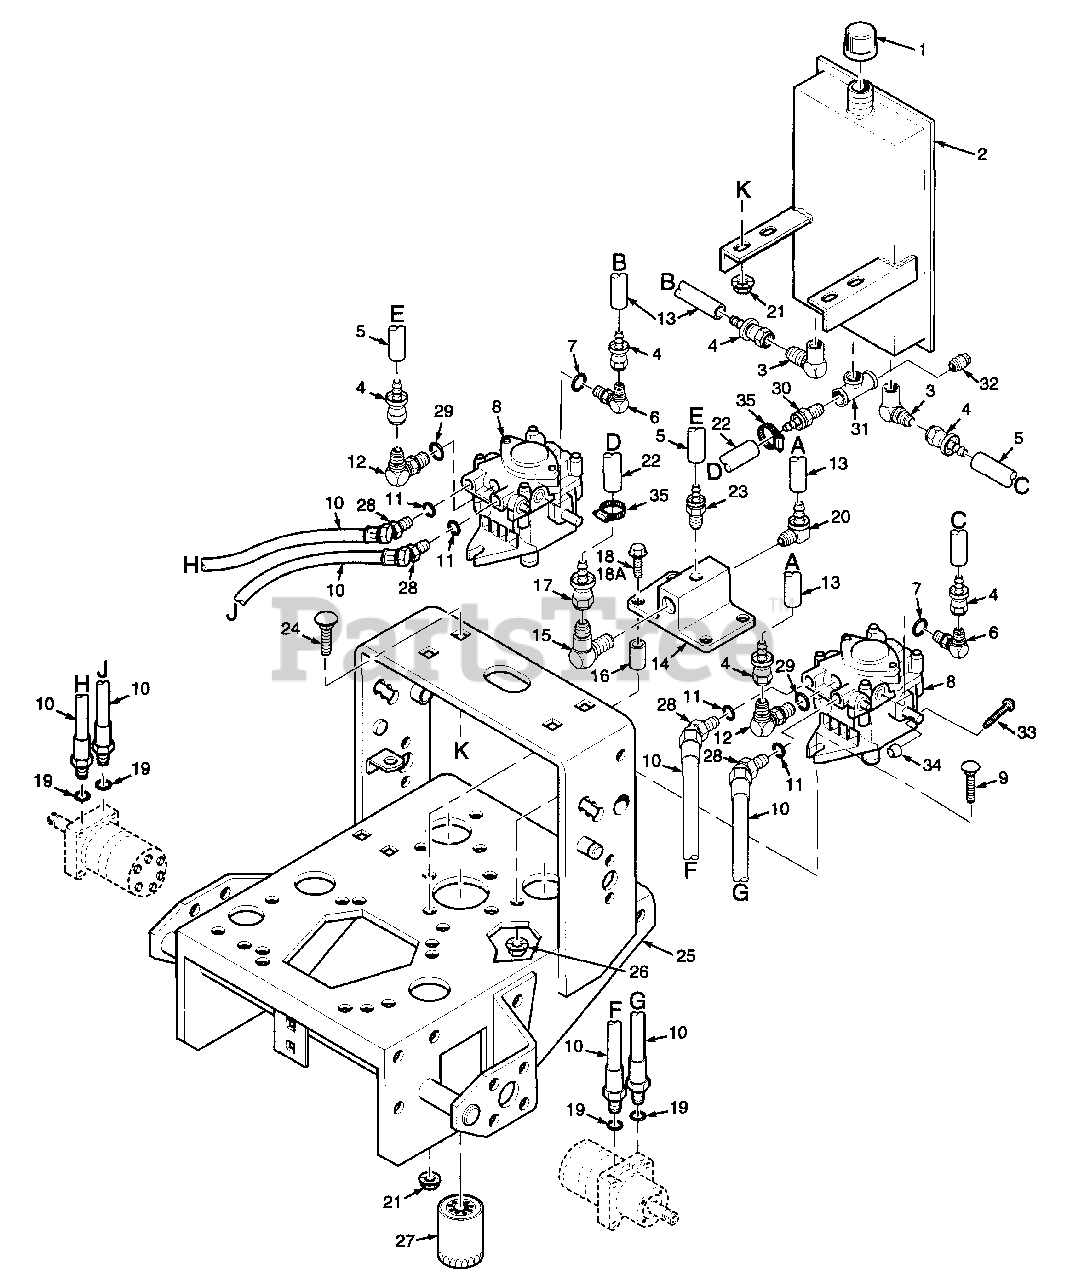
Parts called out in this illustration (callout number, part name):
1	Cap, Oil Reservoir
2	Oil Reservoir (Large Frame)
3	Elbow, 90 deg. Female 1/4 NPT to 1/4 JIC Male
4	Coupling, 7/16-20 SAE Flare Swivel to 1/4" Hose Push On
5	Hose, 1/4" ID - 12" Long
6	Elbow, 90 deg. 7/16-20 JIC to 9/16-18 "O" Ring
7	O-Ring
8	Pump, Hydro-Gear BDP-10L117
9	Bolt, Carriage, 3/8-16 x 1-1/4"
10	Nose, Pump to Motor
11	O-Ring
12	Elbow, 90 deg., 7/16-20 JIC x 7/16-20 O-Ring
13	Hose, 1/4" ID - 10" Long
14	Oil Filter Base
15	Elbow, 90 deg. Male 3/4-16 JIC to 1/2" Male NPT
16	Spacer, Oil Filter Base (20" Frame)
17	Coupling, 3/4-16 SAE to 1/2" Hose Push On
18	Capscrew, 5/16-18 x .75" (For 16") Serr. Flange
18A	Capscrew, 5/16-18 x 2.25" (For 20") Serr. Flange
19	O-Ring
20	Elbow, 90 deg. Male 1/4 NPT to 1/4 Hose Push On
21	Nut, 5/16-18 Serr. Flange
22	Hose, Formed 1/2" ID
23	Coupling, 1/4 straight Male NPT to 1/4 Hose Push On
24	Bolt, 5/16-18 x 3/4" Carriage
25	Engine Deck (16" Wide) W/Decals
26	Nut, 3/8-16 Serr Flange
27	Oil Filter
28	Elbow, 45 Deg. - 3/4-16 JIC Male x Male 3/4-16 O-Ring
29	O-Ring
30	Coupling, 3/8 Pipe to 1/2 Push-on
31	T-Fitting, 3/8 NPT
32	Plug, 3/8-18 NPTF Magnetic
33	Screw, 1/4-20 x 2.0" Round Head Phillips
34	Nut, 1/4-20 Elastic Stop
35	Clamp, .87 max dia.
